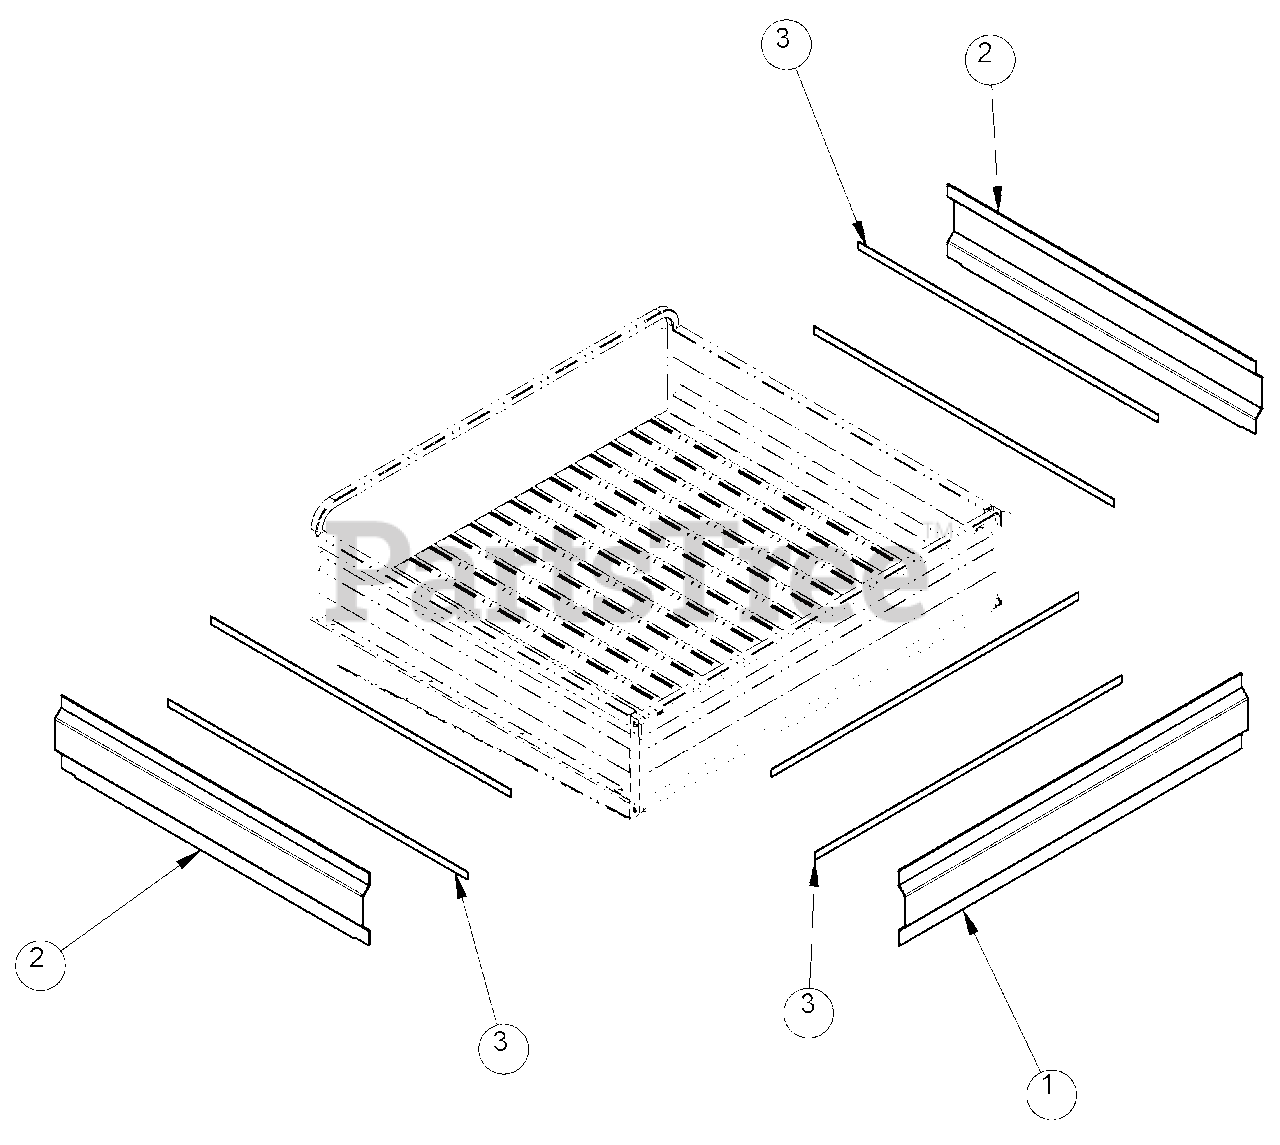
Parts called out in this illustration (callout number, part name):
1	PANEL, TAILGATE CAMO
2	PANEL, SIDE CAMO
3	TAPE, DOUBLE-SIDED
